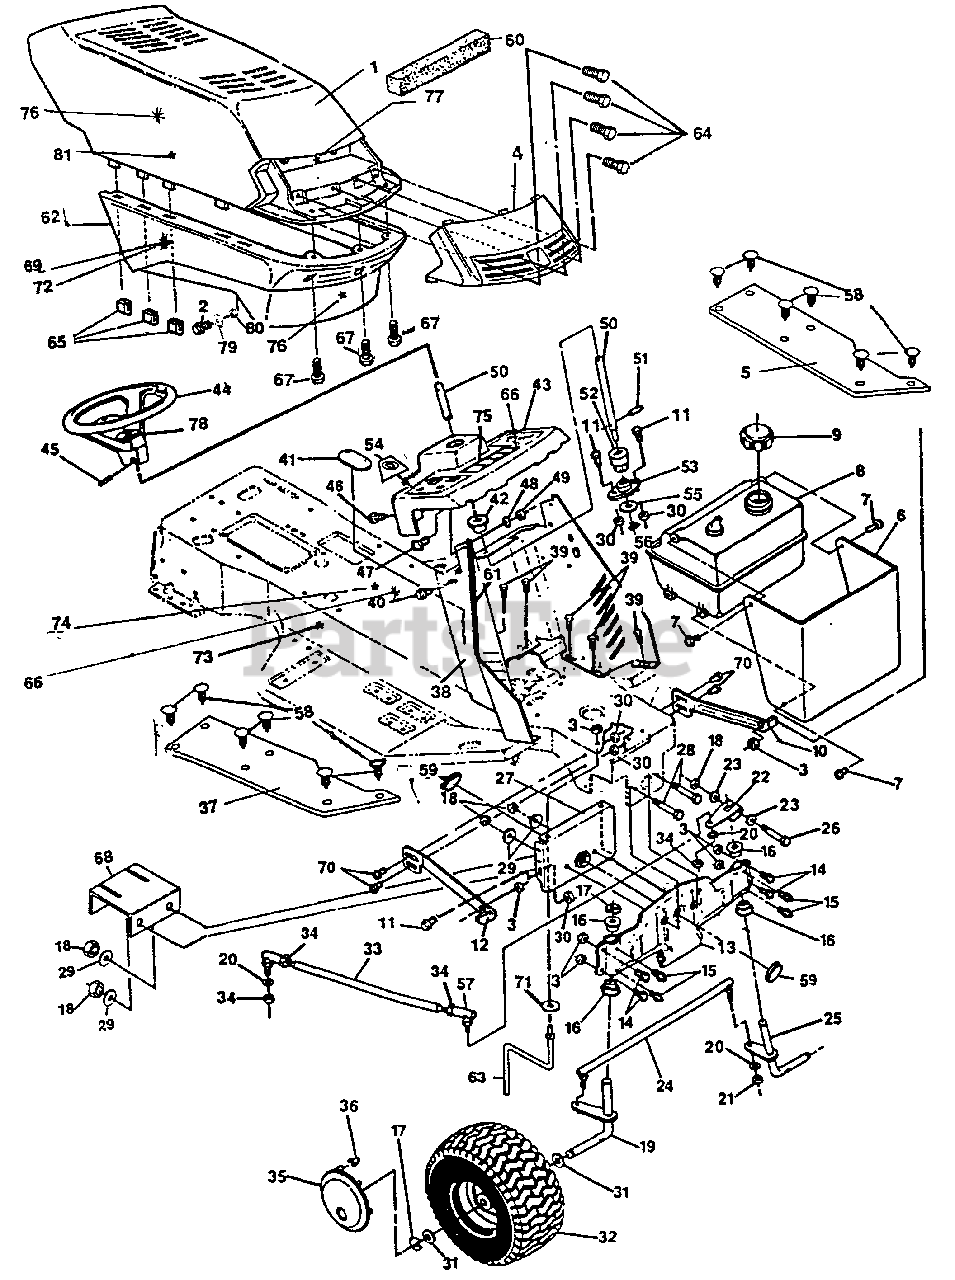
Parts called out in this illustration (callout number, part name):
2	Shoulder Bolt, 5/16-18 Thd.
3	Nut, Hx, Ctrlk, 5/16-18 Thd.
4	Lens, Headlight
5	Assembly, Foot Pad L.H.
6	Heat Shield
7	Screw, Hx Hd, Plastite 1/4 x 3/4
8	Tank, Gas 1.5 W/ Sensor
8	Low Fuel Sensor
9	Cap, Fuel
10	Bracket, Hood L.H.
11	Screw, Hx Hd, Wd Fl 5/16-18 x 3/4 In.
12	Bracket, Hood R.H.
13	Front Axle W/Bearings & Spindles
14	Screw, Hx Hd, 5/16-18 x 5/8 In.
15	Grease Fitting
16	Bearing, Spindle
18	Nut, Hx, Ctrlk, 3/8-16 Thd.
19	Spindle, R.H.
20	Washer, Split, Lock 3/8 In.
21	Nut, Hx, 3/8-24 Thd.
22	Steering Arm, Upper
23	Washer, Flat, 25/64 In.
24	Assembly, Tie Rod
25	Spindle, L.H.
26	Screw, Hx Hd, 3/8-16 x 2-1/2 In.
27	Support Bracket, Front Axle
28	Screw, Hx Hd, 3/8-16 x 3 In.
29	Washer, Spring
30	Nut, Hx, Wd Fl Lk 5/16-18 Thd.
31	Washer, Flat, 3/4 In.
32	Wheel & Tire Assembly, Front
32	Valve Stem
33	Drag Link
34	Nut, Hx, Jam, 3/8-24 Thd.
35	Hubcap, Front
36	Clip, Hubcap
37	Assembly, Foot Pad R.H.
38	Dash, Lower
39	Screw, Tap, 5/16-18 x 3/8 In.
40	Screw, Self-Tap, 1/4-20 x 1/2 In.
42	Bushing, Upper Steering
43	Dash, Upper
44	Steering Wheel
45	Pin, Spring, 1/4 x 2 In.
46	Screw, Tap, 1/4-20 x 1/2 In.
47	Screw, Hx Hd, 1/4-20 x 5/8 In.
48	Washer, Flat, 9/32 In.
49	Nut, Hx, Ctrlk, 1/4-20 Thd.
50	Shaft, Steering
51	Pin, Dowel
52	Pinion, Steering
53	Bearing, Flange
54	Plate, Electric Clutch
55	Washer, Flat, 1/2 In.
57	Ball, Joint, 3/8 Thd.
58	Ratchet Fastener
59	Plug, Front Axle
60	Foam, Hood Baffle
61	Wide Trim 18"
63	Belt Guide
64	Screw, #4-24 x 1/2 In.
65	Clip, Tinnerman
66	Decal, Depress Clutch Brake
67	Screw, #10 x 1/2 In.
68	Bracket, Stop
69	Decal, Pin Stripe R.H.
70	Screw, Hex Wd Fl, 5/16-18 x 3/4 In.
71	Washer, Internal Tooth
72	Decal, Pin Stripe L.H.
73	Decal, Wheel 4 Steer Husq.
74	Decal Oper Instr ERO Top Frame
75	Decal, Dash, Chg, Oil, Fuel All Systems
76	Decal, Fender Rear, Hood Husq.
77	Decal, Reflector Ver II Hood
78	Decal, Gunsight Cent. Steer Whl.
79	Flat washer
80	Nut, 5/16-18
81	Decal, Model #4140H
